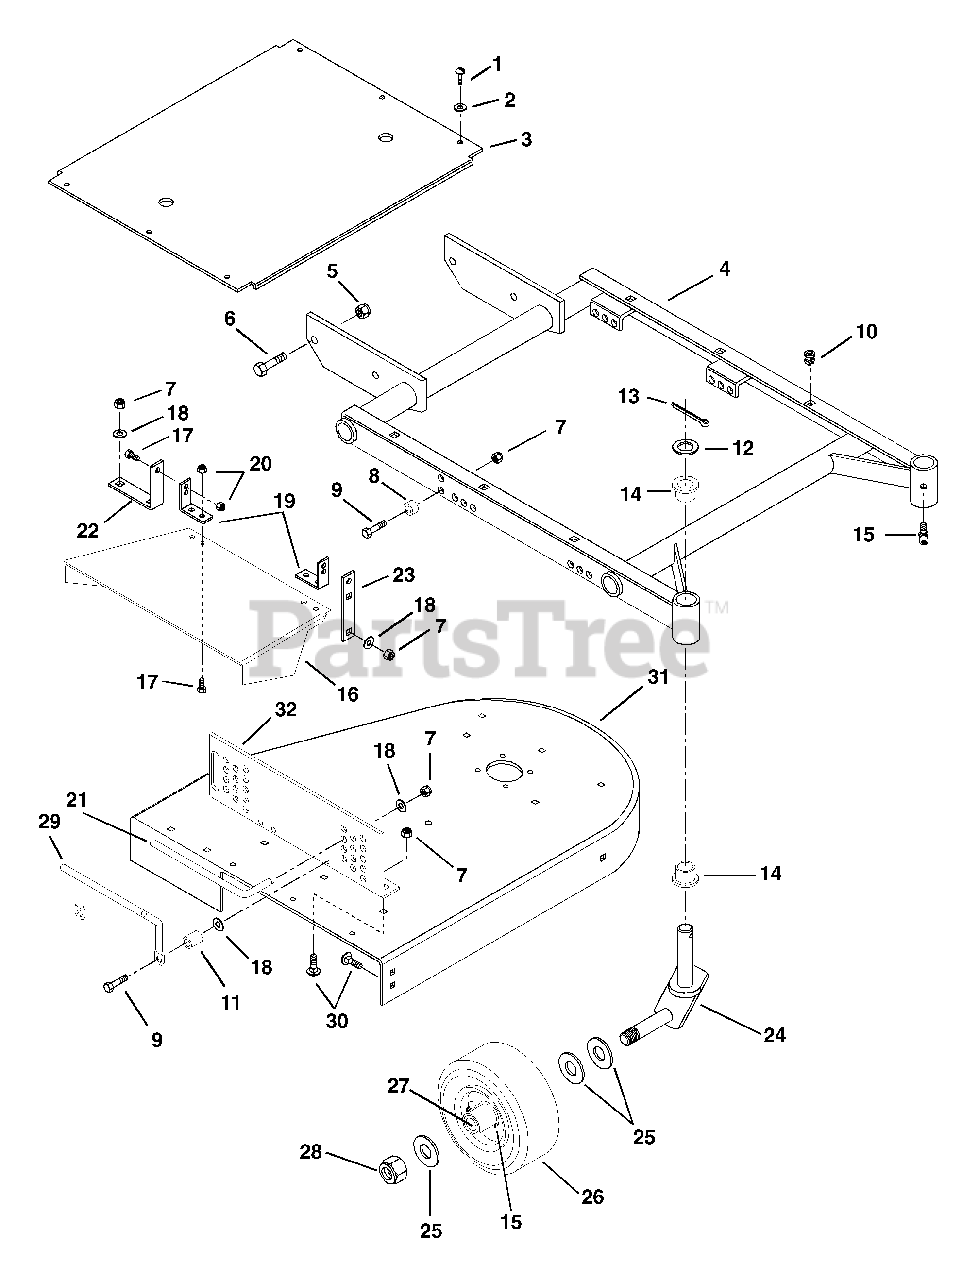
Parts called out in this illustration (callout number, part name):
1	Screw-Tapping .25-20 x .50
2	Washer-Flat-Steel .281 x .625 x .065
3	Cover, Silkscreen
4	Weldment, Mower Frame
5	Nut-Locking-Nylon .625-11 Grade 2
6	Bolt-Hex .62-11 x 1.50
7	Nut-Locking-Nylon .375-16 Grade 2
8	Bushing .391 x .626 x .670
9	Bolt-Hex .38-16 x 1.50 Grade 5
10	Grommet, Plastic
11	Bushing
12	Washer-Hardened-Thrust 1.002 x 1.552 x .030
13	Pin-Cotter .188 x 1.50
14	Bushing-Flange 1.020 x 1.385 x .75 x 1.75
15	Fitting-Lube .25-28 x .256
16	Chute, Discharge
17	Bolt-Hex .31-18 x .75 Grade 5
18	Washer-Flat-Steel .406 x .812 x .065
19	Bracket
20	Nut-Locking-Nylon .312-18 Grade 2
21	Pin, Mower Locking
22	Bracket
23	Bracket
24	Weldment, Castor Fork
25	Washer-Flat .812 x 1.469 x .134
26	Wheel 9 x 3.50
27	Bearing, Gauge Wheel
28	Nut-Locking-Nylon .75-10 Grade 2
29	Handle
30	Bolt-Round Head Square Neck .38-16 x 1.0
31	Weldment, 36" Deck
32	Bracket, Mower Side Support Left Hand
32	Bracket, Mower Side Support Right Hand
